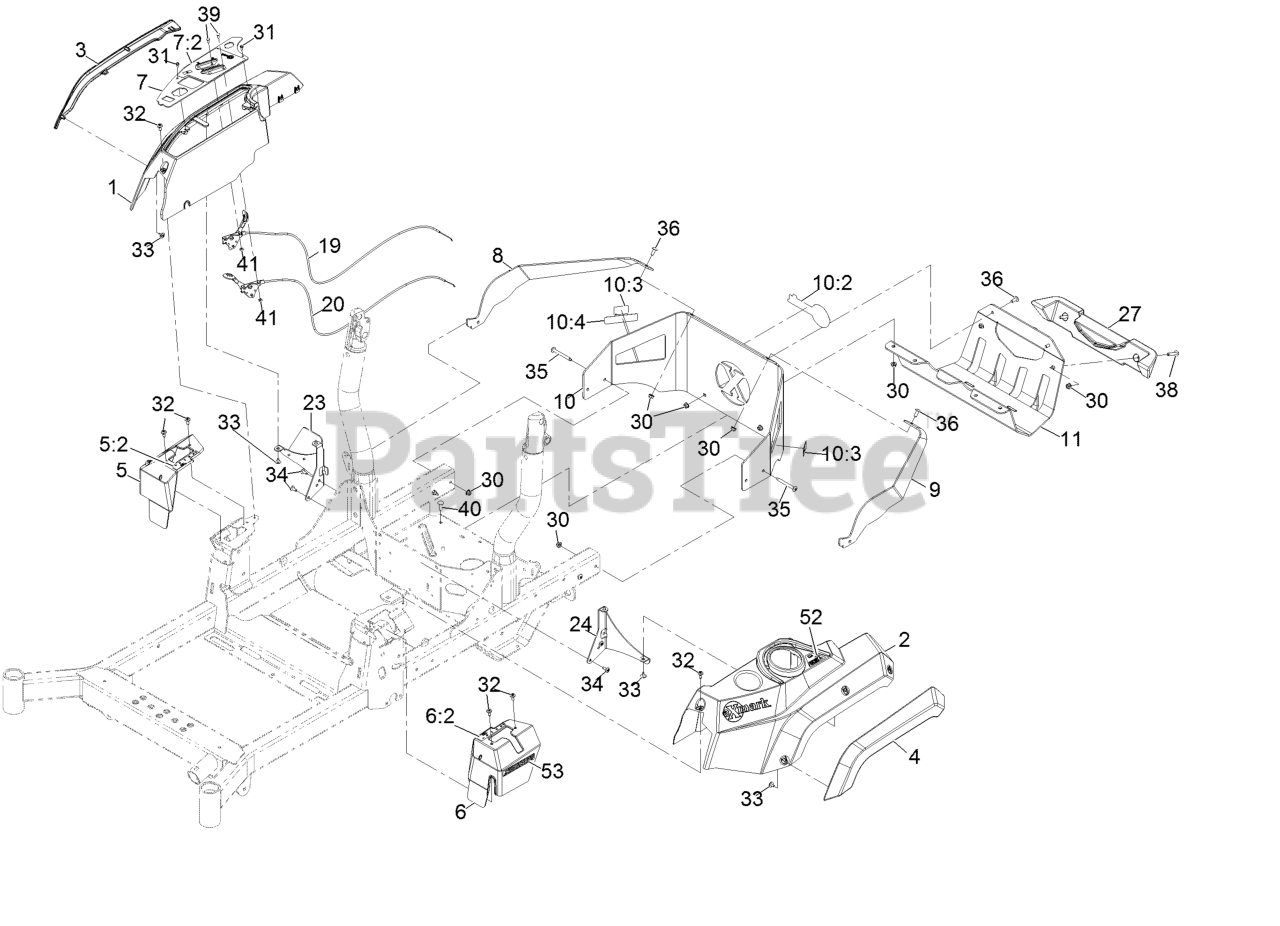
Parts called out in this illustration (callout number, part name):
1	Console-Exmark, RH
2	Console, LH
3	Fender-RH
4	Fender-LH
5	Cover-Control, Motion (RH)
5:2	Decal-Control, Motion (RH)
6	Cover-Control, Motion (LH)
6:2	Decal-Control, Motion (LH)
7	Ctrl Panel ASM W/Decal
7:2	Decal-Control Panel
8	Support-Upper, RH
9	Support-Upper, LH
10	Rear Guard ASM
10:2	Decal-Exmark Logo
10:3	Decal-Warning
10:4	Decal-Arrester, Spark
11	Guard-Muffler
19	Cable-Control, Choke
20	Cable-Control, Throttle
23	Support-Console, RH
24	Bracket-Console, LH
30	Nut-Nyloc 5/16-18 Flg
31	Screw-HWH #10-14 X 1/2
32	Screw-1/4-20 X 1/2 Tf Torx Plus
33	Screw-HWH #10-14 X 1/2 Torx
34	Screw-1/4-20 X .65 Torx Plus
35	Screw-Truss HD 5/16-18 X 2 3/4 Torx Plus
36	Screw-Truss HD 5/16-18 X 3/4 Torx Plus
38	Screw-Truss HD 5-16-18 X 1 1/2 Torx Plus
39	Bolt-Carriage #10-24 X 1/2
40	Bolt-Carriage 5/16-18 X 1 Sp
41	Nut-Nyloc #10-24
52	Decal-Fill, Fuel
53	Decal-X-Series
